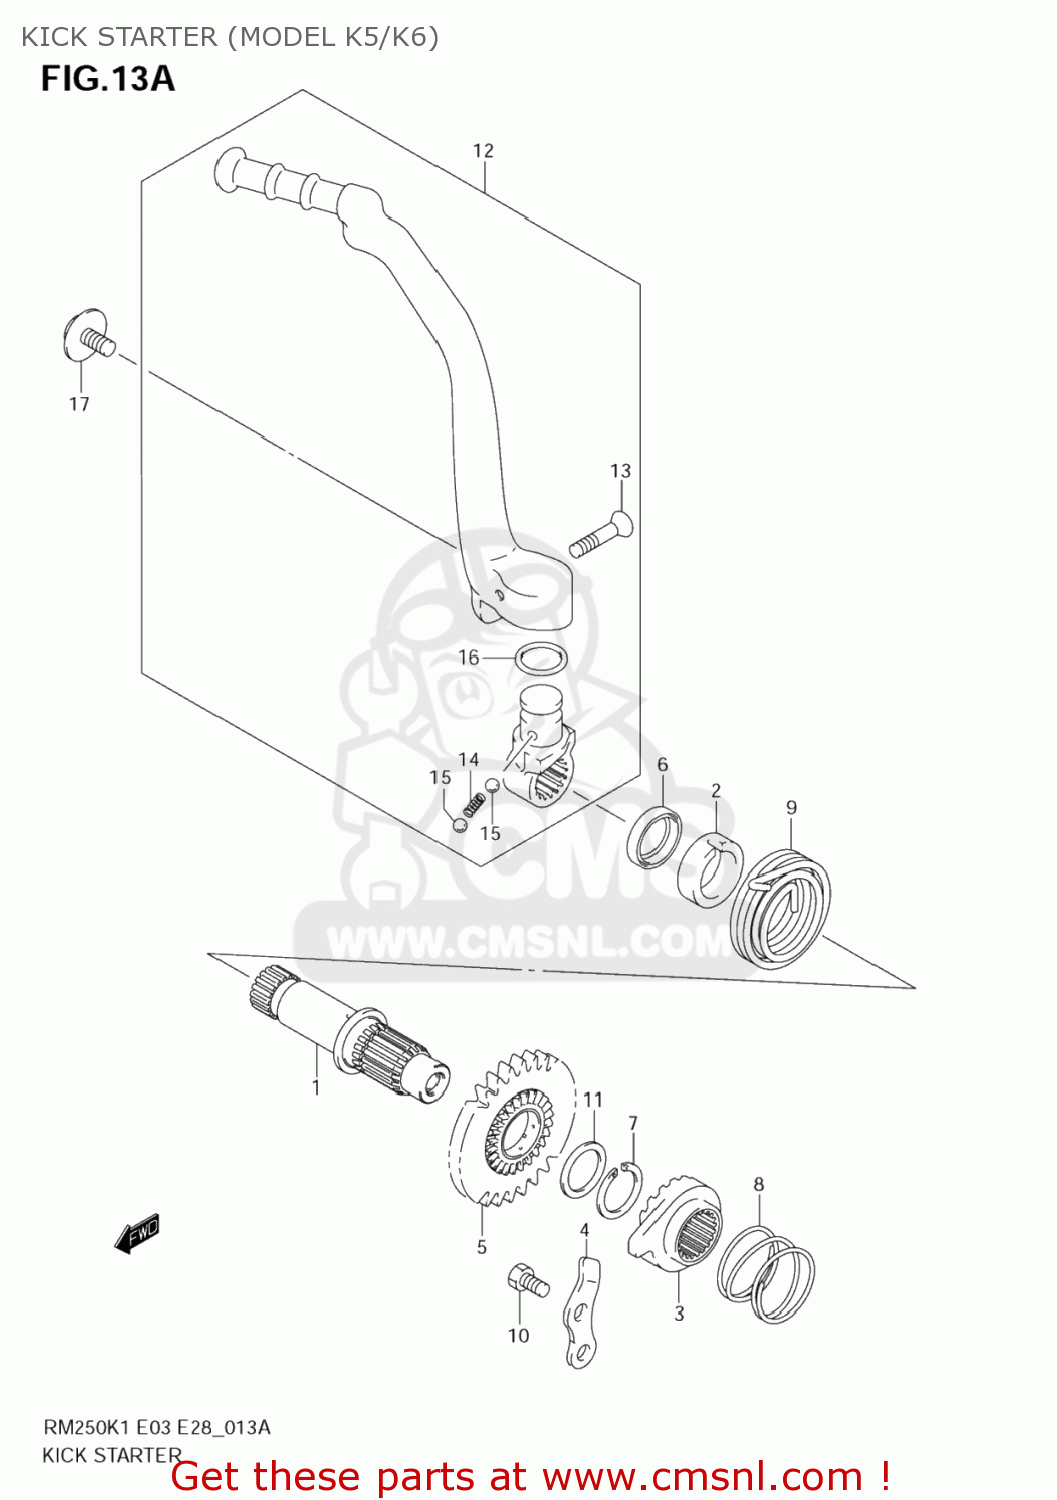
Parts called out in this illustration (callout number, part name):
1	SHAFT,KICK STARTER
2	GUIDE,KICK STARTER SFT SPRING
3	STARTER,KICK
4	GUIDE,KICK STARTER
5	GEAR,KICK STARTER DRIVE(NT:28)
6	SEAL,OIL(20X27X5)
7	CIRCLIP
8	SPRING
9	SPRING
10	BOLT
11	SHIM(22X28X1)
12	LEVER ASSY,KICK STARTER
13	SCREW(6X27.5)
14	SPRING
15	BALL
16	O RING,KICK STARTER
17	BOLT(8X14)
